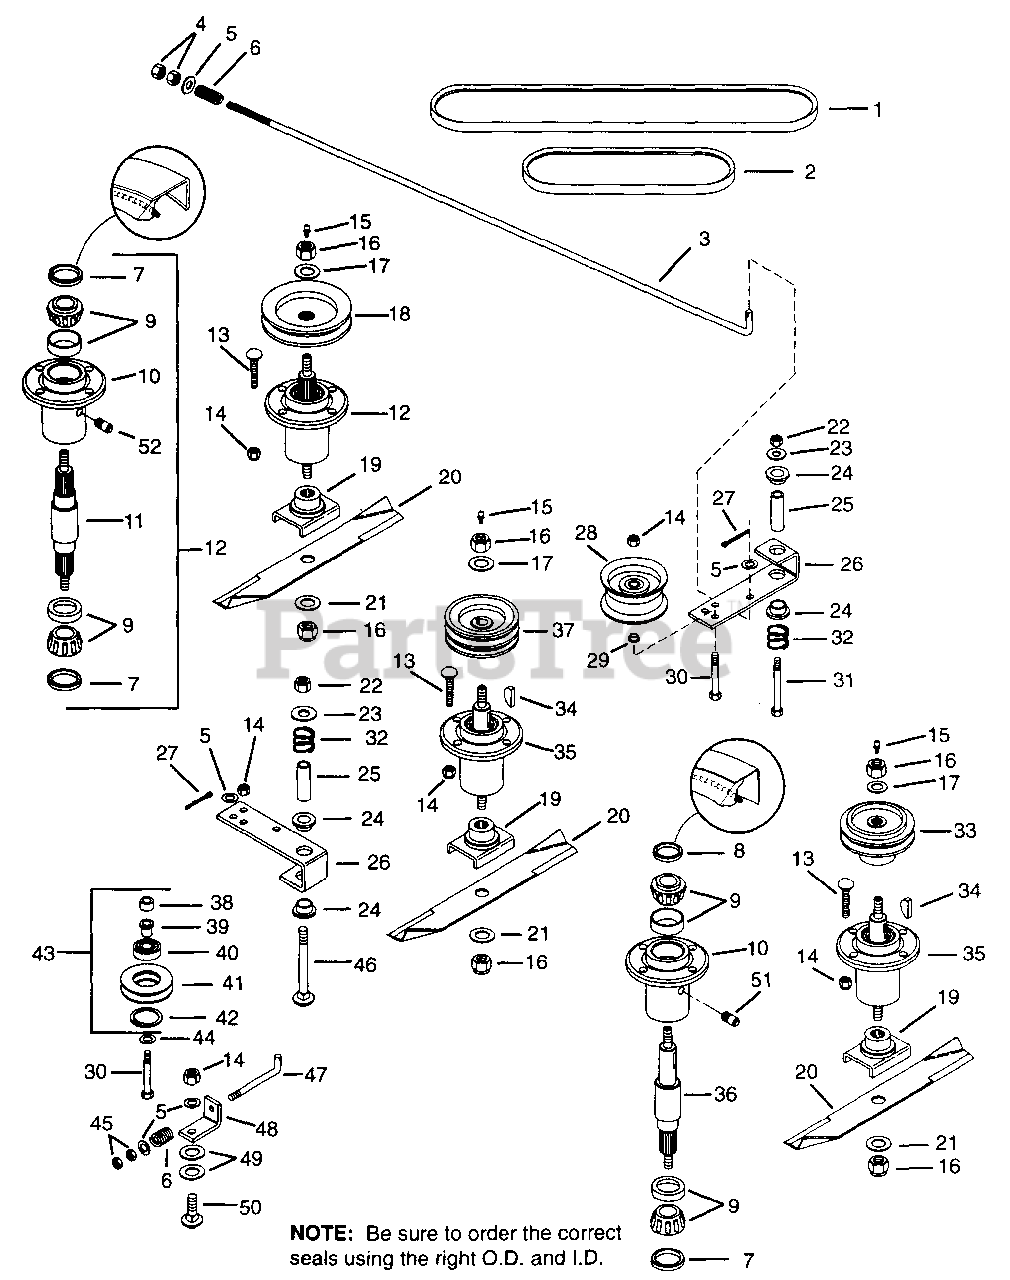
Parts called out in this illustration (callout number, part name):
1	V-Belt A-Section 42.4 x .531
2	V-Belt A-Section 24.90 x .500/.031
3	Rod, Idler
4	Nut-Hex .375-24 Grade 2
5	Washer-Flat-Steel .406 x .812 x .065
6	Spring-Compression .125 x .78 x 1.00
7	Seal 1.987 x 1.375 x .313
8	Seal 1.987 x 1.500 x .313
9	Assembly, Bearing Cup & Cone
10	Bearing Housing
11	Shaft, Spindle
12	Service Kit Spindle Assembly
13	Bolt-Round Head Square Neck .38-16 x 1.375
14	Nut-Locking-Flange .75-10
15	Fitting-Lube .125
16	Nut-Locking-Nylon .625-11 Grade 2
17	Washer-Flat-Steel .687 x 1.312 x .150
19	Weldment Blade Cradle
20	Blades 60"
21	Washer-Flat-Steel .656 x 1.312 x .095
22	Nut-Locking .50-13
23	Washer-Flat-Steel .531 x 1.250 x .100
24	Bushing-Flange .762 x 1.0 x .580 x 1.48
25	Spacer .560 x .750 x 2.437
26	Arm, Idler Pivot
27	Pin-Cotter .09 x 1.0
28	Idler-Flat 4-.687 x .38
29	Bushing-Flange .406 x .88 x .270 x .140
30	Bolt-Hex .38-16 x 2.25 Grade 5
31	Bolt-Hex .50-13 x 3.50 Grade 5
32	Spring-Compression .085 x .80 x 1.00
34	Key-Woodruff .25 x .88
35	Service Kit Spindle Assembly
36	Shaft, Spindle
37	Sheave
38	Bushing, Steel .406 x .625 x .480
39	Bushing-Flange .786 x 1.0 x .79
40	Bearing-Ball 1.85 x .787 x .55
41	Sheave, Idler
42	Ring-Retaining-Internal 2.054 x .062
43	Assembly, Idler Sheave
44	Washer-Flat-Steel .375 x 1.125 x .065
45	Nut-Hex .375-16 Grade 2
46	Bolt-Round Head Square Neck .50-16 x 3.50
47	Rod, Idler
48	Bracket, Belt Tensioner
49	Washer-Flat-Steel .531 x 1.062 x .095
50	Bolt-Round Head Square Neck .38-16 x 1.25
51	Relief Fitting Grease
